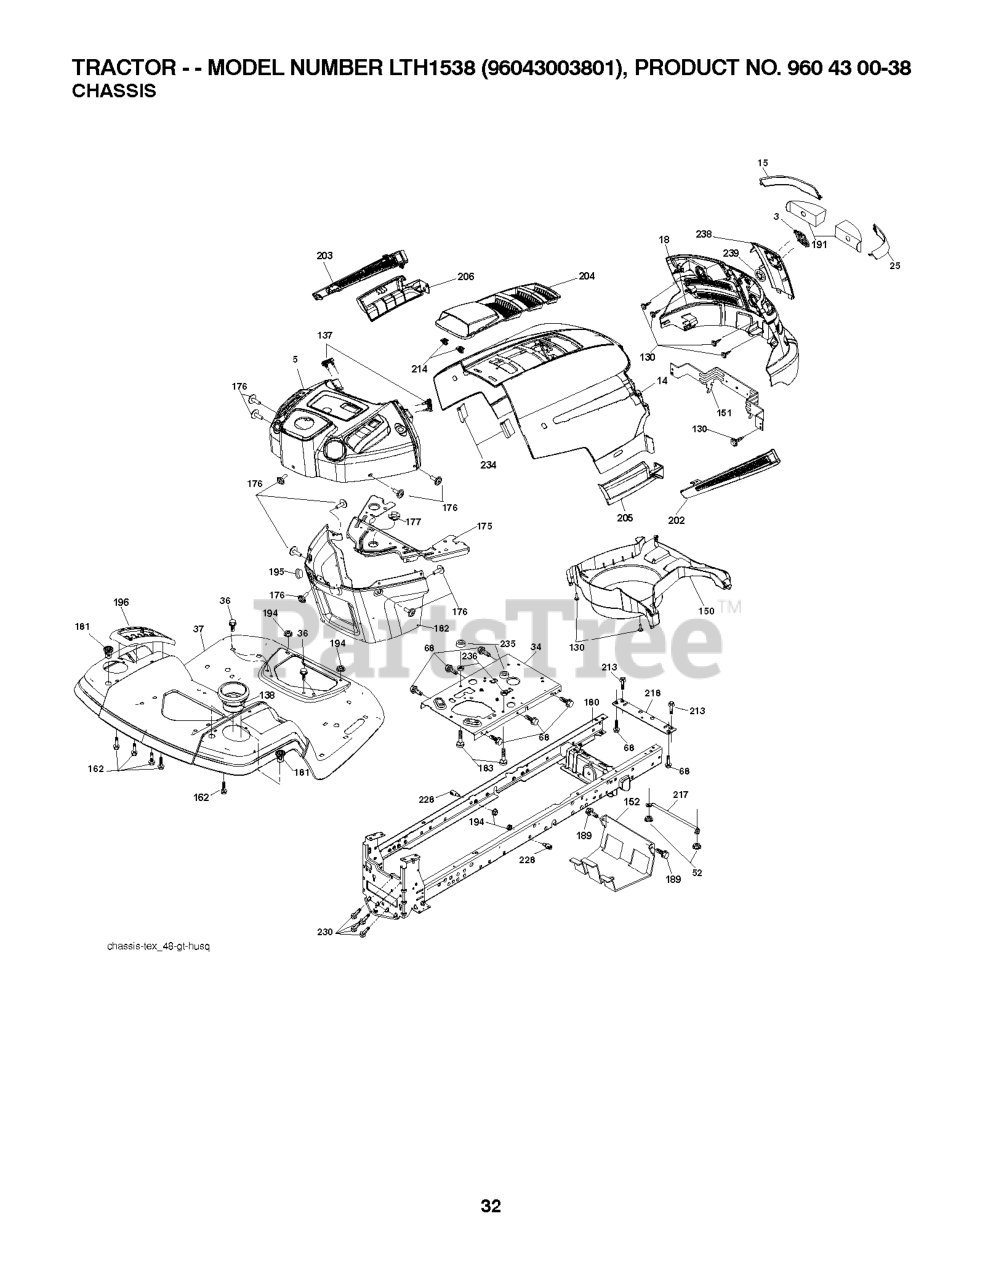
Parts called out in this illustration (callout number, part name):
3	RP LOGO
5	DASH
14	HOOD
15	LENS.HUSQVARNA LT.LH
18	RP GRILLE/LENS ASM.
25	LENS.HUSQVARNA LT.RH
34	PLATE.ENGINE.WELDED.CHASSIS
36	SCREW 5/16"
37	FENDER.REAR.ORANGE
52	LOCKNUT
68	Screw 5/16-18 x 1/2 Hex, Self Tapping 5/16-18 x 1/2
130	SCREW
137	BUMPER DASH
138	CUPHOLDER.TL.TEX.418
151	BRACKET PIVOT
152	SHIELD.BROWNING.W/TEX
162	SCREW.HI-LO.CONSOLE
175	CROSSMEMBER
176	SCREW.#10-24X5/8.RN.QU
177	BUSHING STEERING
180	CHASSIS
181	BUSHING.MNT.FEND.CRGO.
182	DASH LOWER
183	BOLT.5/16-18X1-1/4 FULL.THREAD
189	SCREW
191	INSERT REFLECTIVE
194	NUT LOCK HEX FLANGE 5/16-18
195	PLUG DASH
196	CONSOLE.ASM.DECK.LIFT.
202	VENT SIDE HOOD RH
203	VENT SIDE HOOD LH
204	VENT TOP HOOD
205	SKIRT SIDE RH
206	SKIRT SIDE LH
213	BOLT
214	CLIP.RETAINER.TINNER.
217	ROD.PIVOT.HOOD
218	X-PIECE.HOOD.STOP.NON/
228	STUD.FASTNER.W/ANTI-ROTATE
230	SHOULDER BOLT 5/16-18TT
234	BUMPER.HOOD.TEX.HUSQVARNA
235	SPACER FENDER
236	NUT.CENTERLOCK.5/16-
238	TRIM
